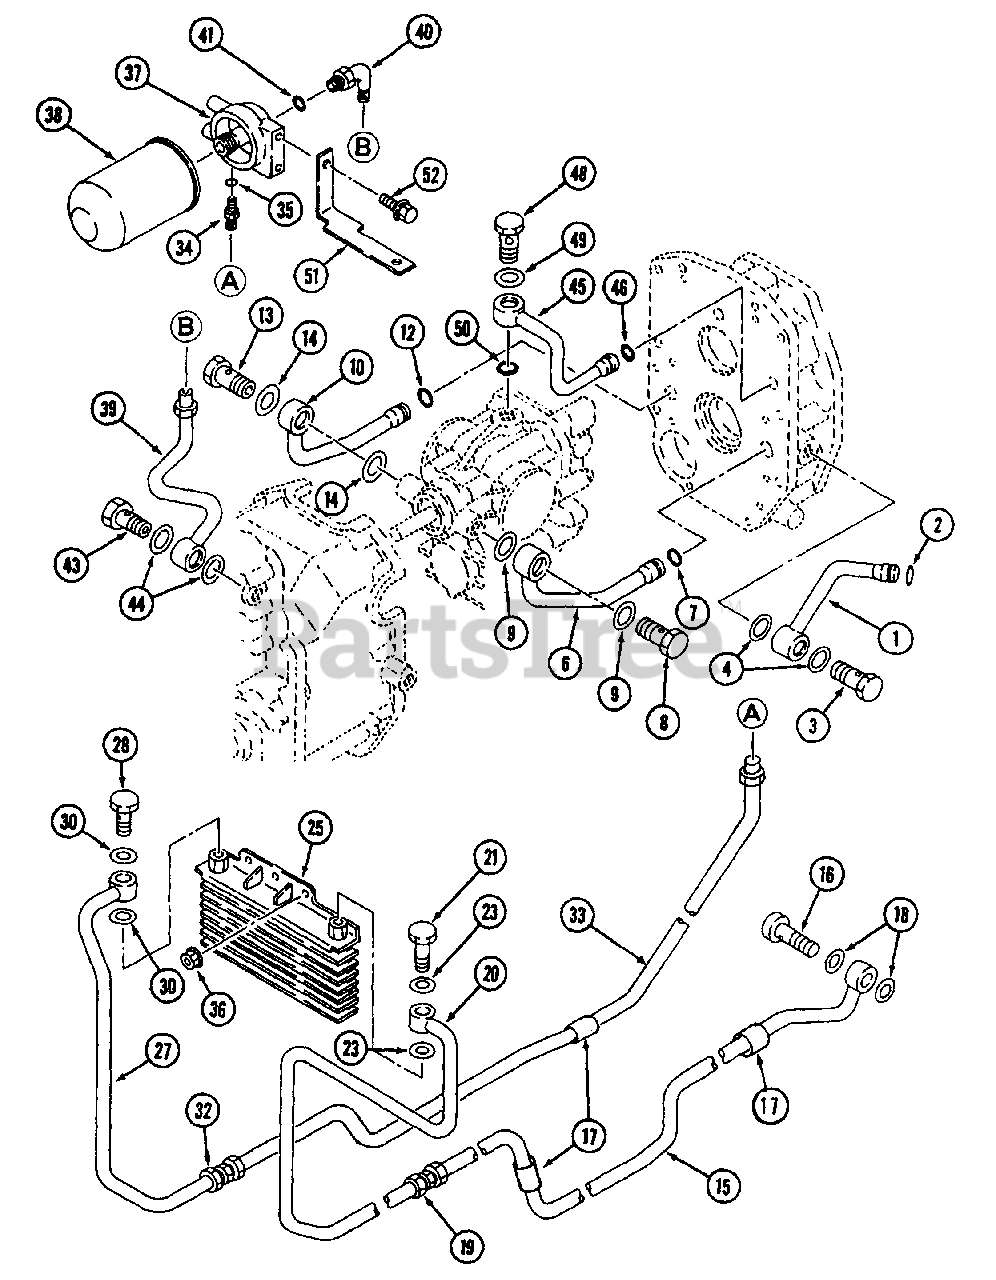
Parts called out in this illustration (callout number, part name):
15	Pipe P Ass'y.
18	Seal, Washer
20	Pipe Q Ass'y.
27	Pipe S Ass'y.
33	Pipe U Ass'y.
34	Body (Nipple)
39	Pipe V Ass'y.
44	Seal, Washer
49	Seal, Washer
